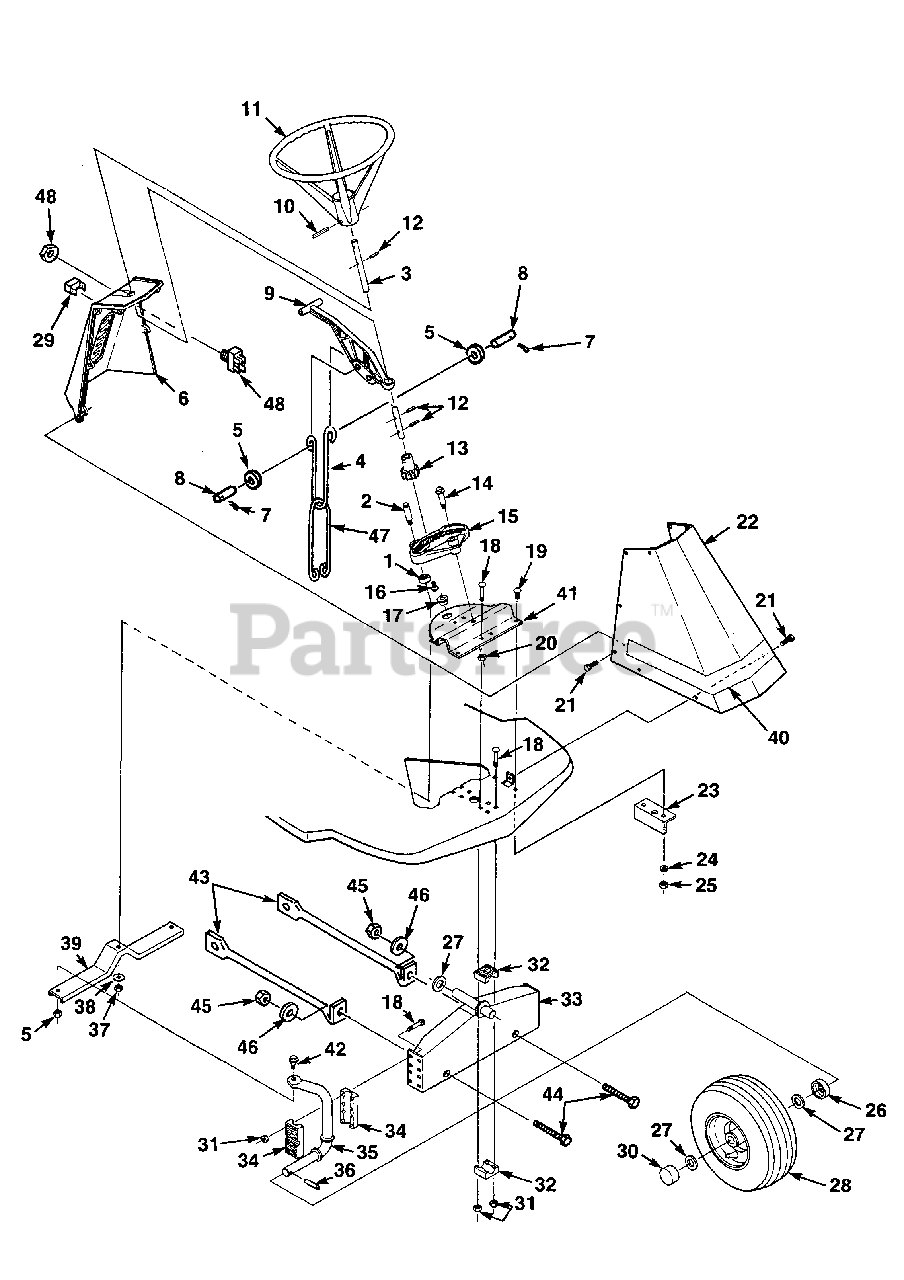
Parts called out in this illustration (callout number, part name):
2	STEER-Stud
4	LINK-Lift
6	PANEL-Console
7	PIN-Cotter
8	PIN-Retainer
9	HANDLE-Lift
11	WHEEL-Steering
15	SECTION-Steering
16	SCREW-1/4-20 x 1/2
25	NUT
26	WASHER-Dust
28	WHEEL & TIRE
29	LIGHT INDICATOR
33	AXLE-Front
35	SPINDLE-LH Wheel
36	PIN
38	WASHER
40	DECAL-Product identification
41	BRACKET-Reinforcement
43	SUPPORT-Frame axle
46	WASHER-Plain
47	LINK-Lower lift
48	SWITCH-PTO
